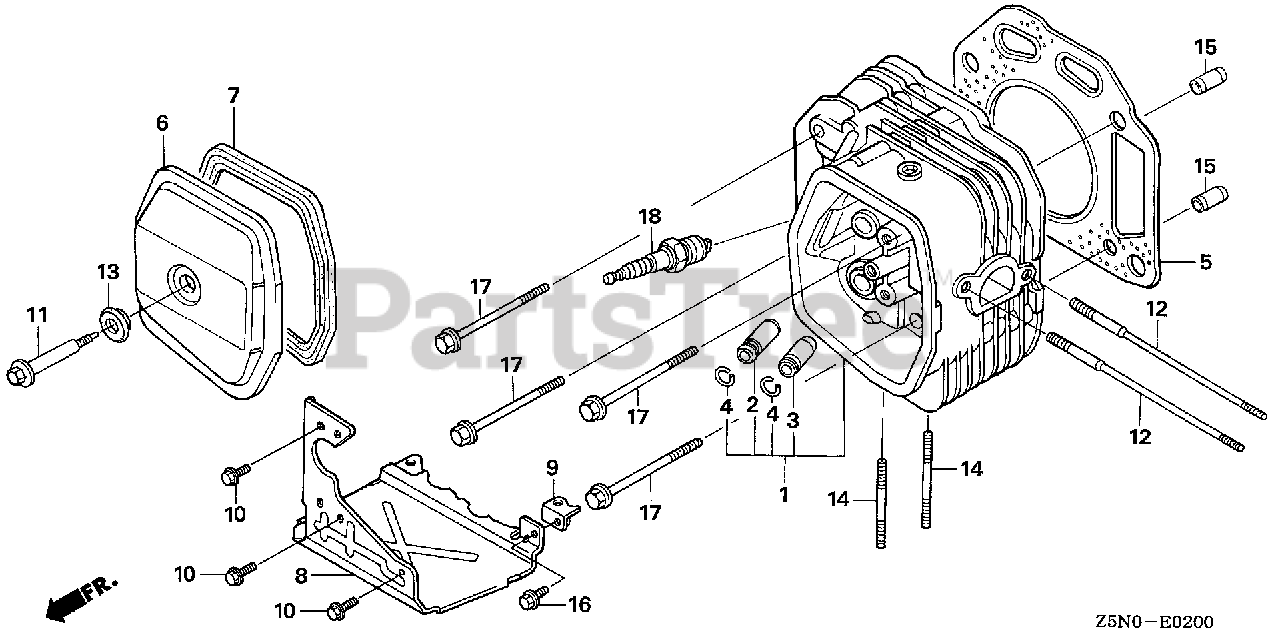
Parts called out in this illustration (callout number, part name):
1	CYLINDER HEAD
2	GUIDE, VALVE (OVER SIZE)
3	GUIDE, EX. VALVE (OVER SIZE)
4	CLIP, VALVE GUIDE
5	GASKET, CYLINDER HEAD
6	COVER, HEAD
7	GASKET, HEAD COVER
8	COVER (LOWER)
9	STAY, COVER (LOWER)
10	BOLT, FLANGE (6X12) (CT200)
11	BOLT, HEAD COVER
12	BOLT, STUD (8X131.5)
13	WASHER, HEAD COVER
14	BOLT, STUD (8X32)
15	PIN, DOWEL (12X20)
16	BOLT, FLANGE (6X12)
17	BOLT, FLANGE (10X80)
18	SPARK PLUG (BPR5ES) (NGK)
